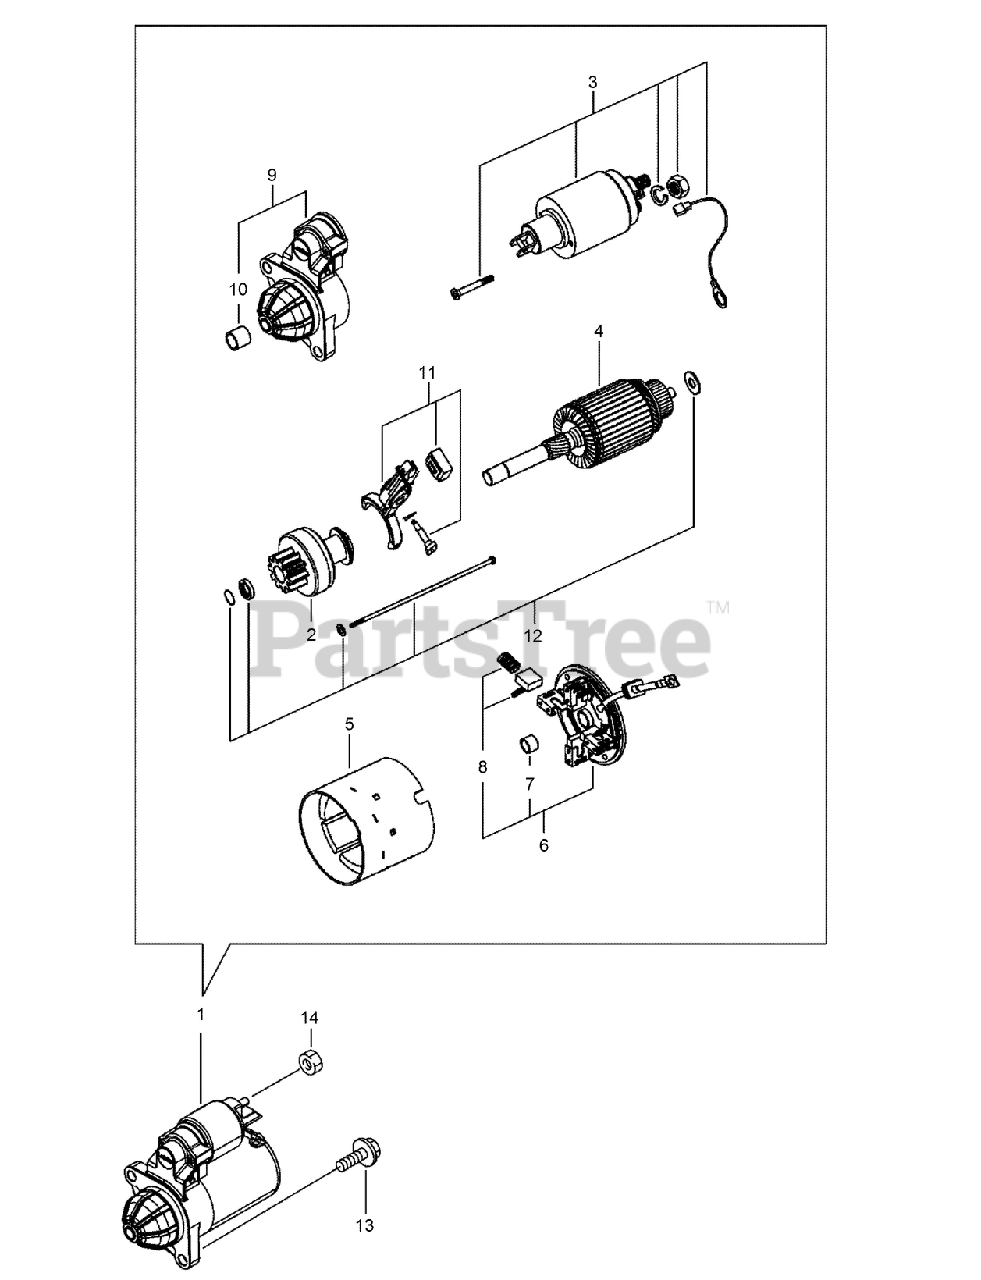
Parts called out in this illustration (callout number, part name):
1	STARTER MOTOR ASM
2	PINION CLUTCH ASM
3	MAGNETIC SWITCH ASM
4	ARMATURE ASM
5	YOKE ASM
6	REAR COVER ASM
7	BUSHING-REAR SIDE
8	BRUSH HOLDER ASM
9	GEAR CASE ASM
10	BUSHING-SIDE, TOP
11	SHIFT LEVER KIT
12	THROUGH BOLT ASM
